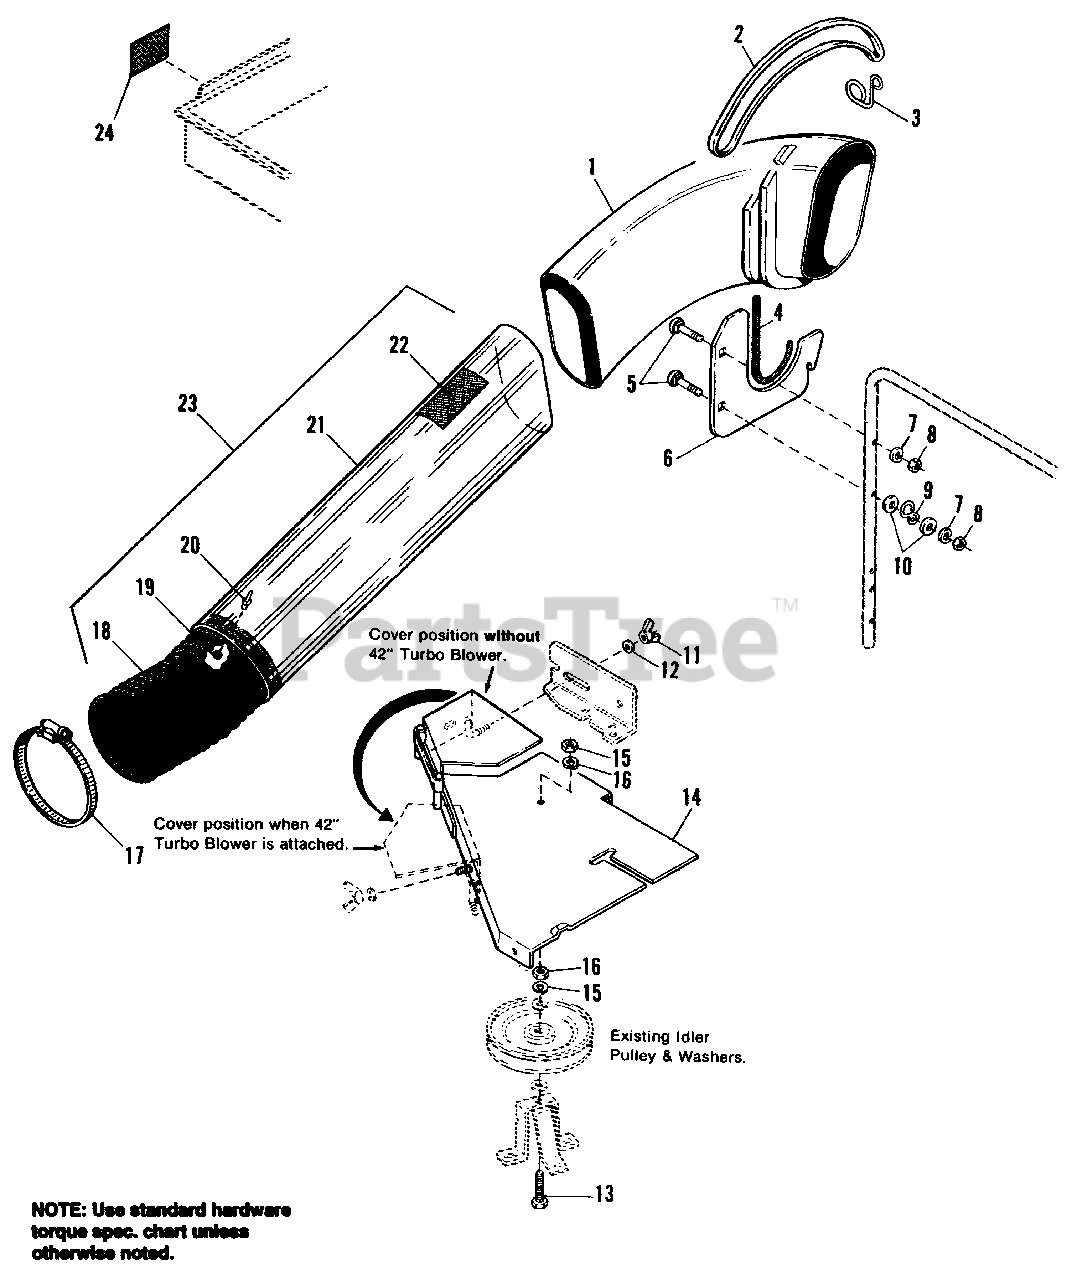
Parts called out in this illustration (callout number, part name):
3	HOOK, Strap
5	BOLT, Rd. Hd., 5/16-18 x 1-3/4
6	BRACKET, Saddle
7	LOCKWASHER, 5/16
8	NUT, Hex, 5/16-18
10	WASHER, 5/16
11	WING NUT, 1/4-20
12	WASHER, 1/4
13	CAPSCREW, Hex Hd., 3/8-16 x 2
14	COVER ASSY., Belt
15	NUT, Hex, 3/8-16
16	LOCKWASHER, 3/8
18	HOSE, Exhaust, 6" I.D.
22	DECAL, Cleaning Inst.
23	TUBE ASSY., (Inc. Ref. Nos. 18-22)
24	DECAL, Warning, Cover
